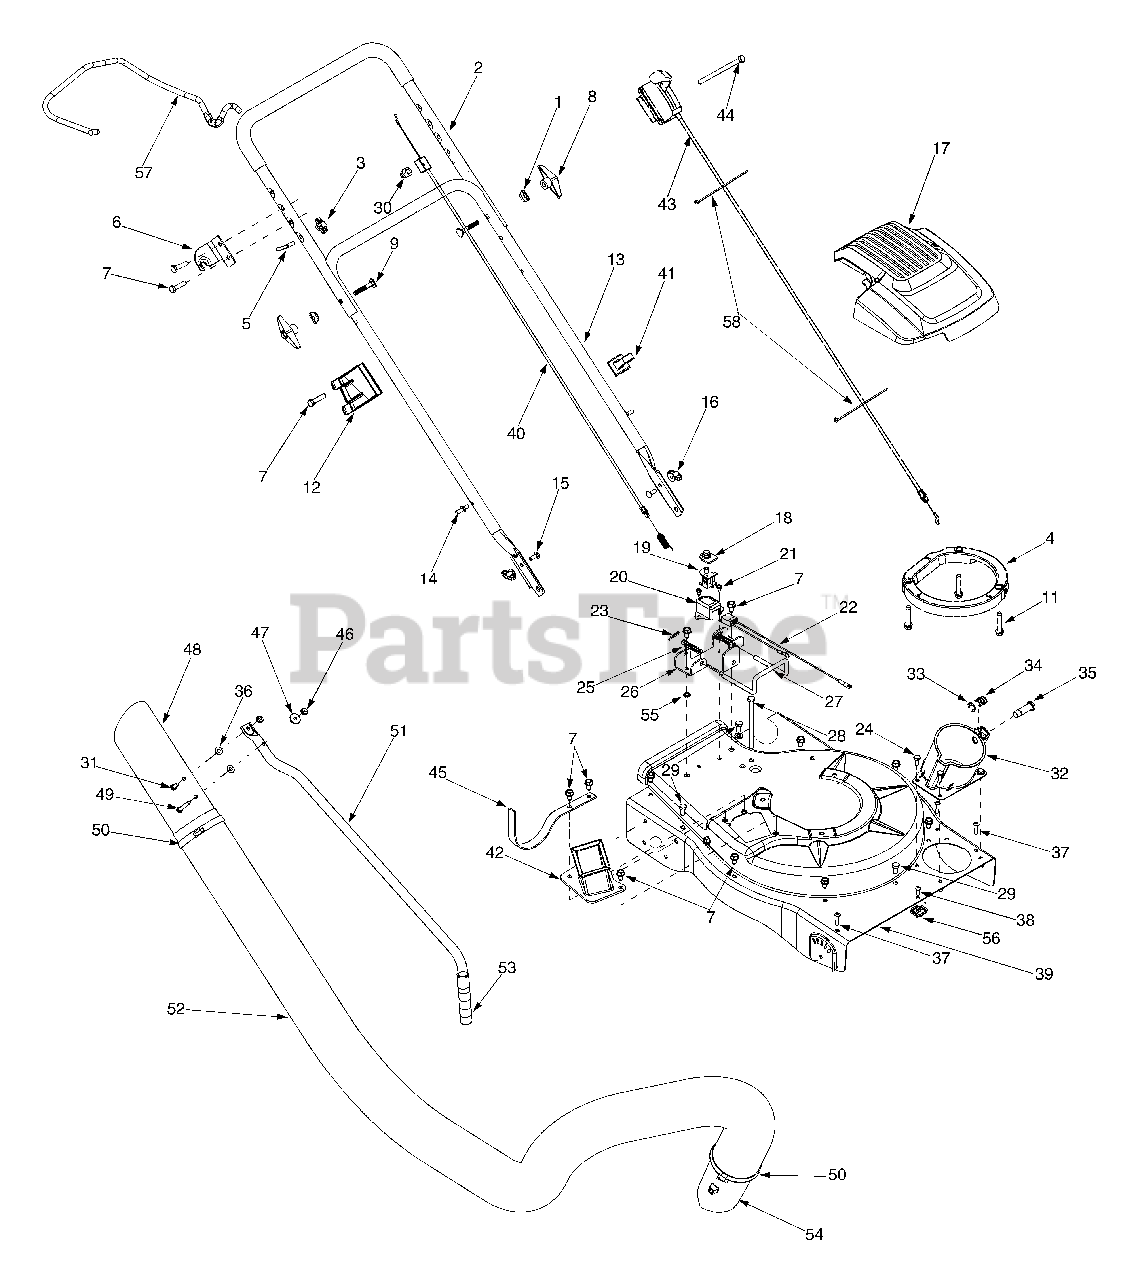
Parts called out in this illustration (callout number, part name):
1	Saddle Washer,.320 x.93
4	Engine Spacer Ass'y
5	Eye Bolt
7	Hex Cap Screw 5/16-12 x.750
8	Handle Knob 5/16-18
9	Carriage Bolt
11	Screw, 3/8-16 x 1.875
12	Lower Hose Handle Bracket
14	Studs
15	Carriage Screw 1/4-20 x.75
16	Wing Nut 1/4-20
18	Switch Cover
19	Safety Switch
20	Safety Switch Cover
21	Hex Washer Screw #10-16 x.50
22	Wire Harness
23	Cotter Pin
24	Screw, 1/4-20 x.500
25	Compression Spring
27	Lock Rod
28	Hex Cap Screw 5/16-18 x 4.5
29	Hex Cap Screw 5/16-18 x.625
30	Cap Lock Nut, 1/4-20
31	Hex Cap Screw 1/4-20 x.620
32	Hose Base Adapter
33	E Ring.500 Dia
34	Compression Spring
35	Clevis Pin
36	Flat Washer.271 ID x.630 OD
37	Screw #12-16 x.750
38	Screw #10 - 16 x.500
41	Cable Guide
43	Speed Control Cable
44	Hex Screw, 1/4-20 x 2.50
47	Spacer
48	Hose Nozzle
49	Hex Cap Screw 1/4-20 x 2.625
50	Adjustment Clamp
52	Vacuum Hose
53	Handle Grip
54	Hose Adapter
55	External L-Washer 5/16
56	Speed Nut
57	Drive Control
58	Cable Tie
